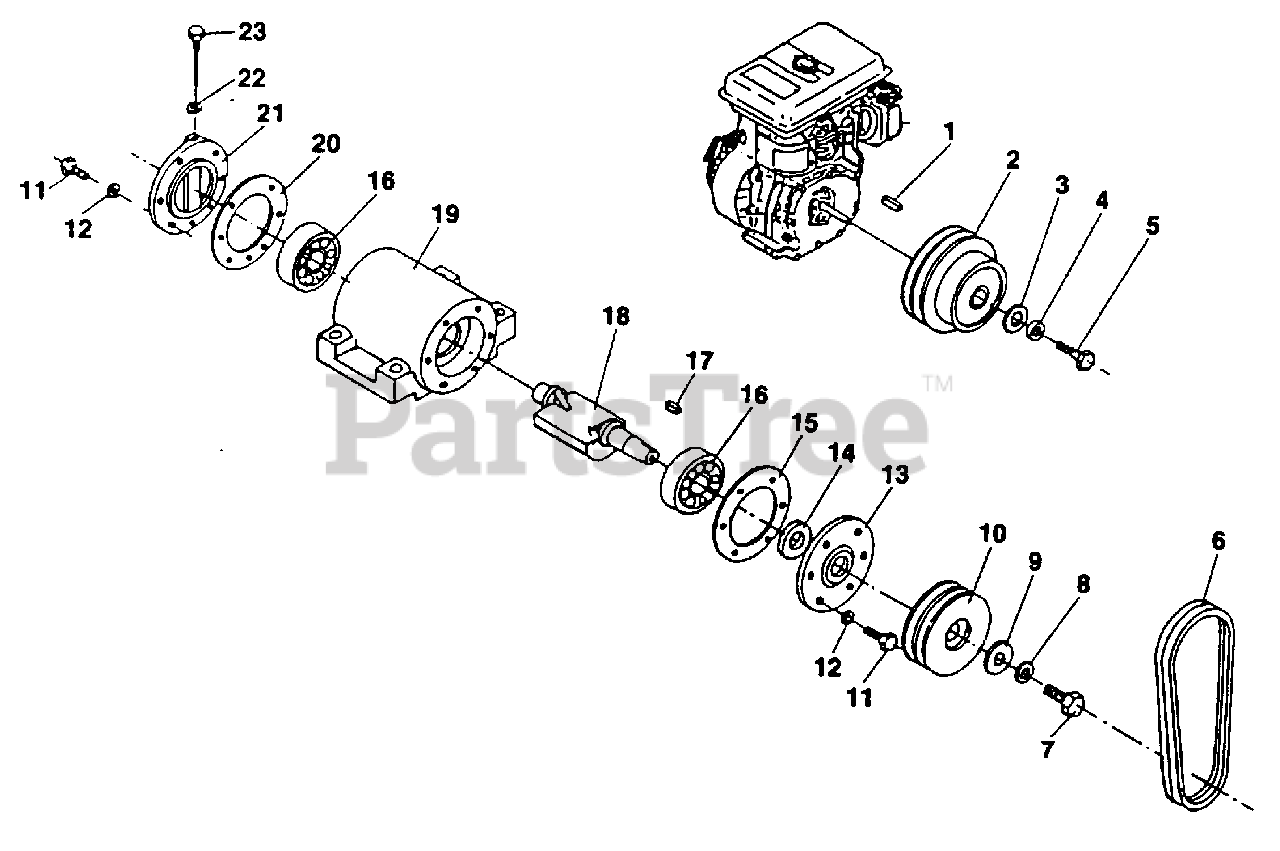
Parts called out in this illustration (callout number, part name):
1	KEY- Parallel
2	CLUTCH- Centrifugal
3	WASHER- Plate (3/8")
4	WASHER- Spring (3/8")
5	BOLT-Hex (3/8 x 1 1/2")
6	BELT- V (A-31)
7	BOLT- Hex (m14 x 30)
8	WASHER- Spring (m14)
9	WASHER- Plate (m14)
10	PULLEY- V
11	BOLT- Hex (m8-20)
12	WASHER- Spring (m8)
13	HOLDER- Bearing
14	SEAL- Oil
17	KEY- Parallel
18	VIBRATION UNIT
19	CASE- Vibration Unit
21	HOLDER- Bearing
22	WASHER- Spring (m16)
23	GAUGE- Oil Level
